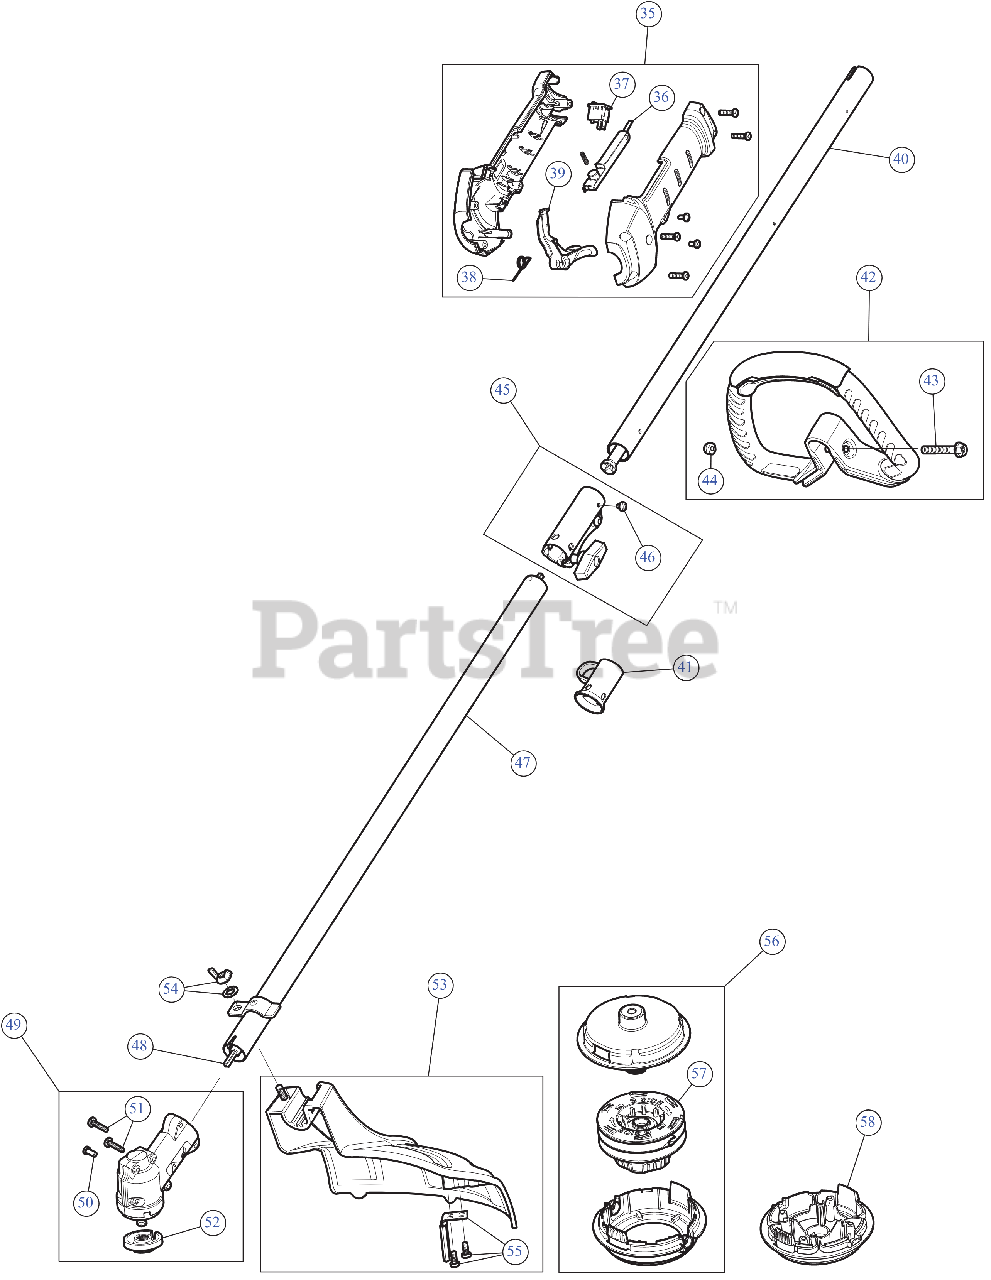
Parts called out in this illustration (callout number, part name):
35	THROTTLE GRIP ASSEMBLY
36	THROTTLE LVR LKOUT
37	SW, MOMENTARY ON/O
38	SPRING TRIG
39	THROTTLE TRIGGER
40	BOOM ASSEMBLY UPR
41	HANGER
42	HANDLE ASSEMBLY
43	BOLT 1/4-20X1 1/2
44	NYLON LOCK NUT
45	COUPLER ASSEMBLY
46	SCREW, 10-32X.250 TA
47	BOOM ASSEMBLY W/BRACKET
48	LOWERIBLE DRIVE SHAFT
49	GEARBOX LCBC
50	SCREW, 8-32 x .312 P
51	SCREW #
52	CUTTING HEAD SPACER
53	GUARD ASSEMBLY
54	BLADE GUARD MOUNTING HARDWARE
55	BLADE ASSEMBLY W/HDW
56	COMPLETE HEAD ASSEMBLY
57	BUMP KNOB
58	CAP ASSEMBLY W/PLUG
